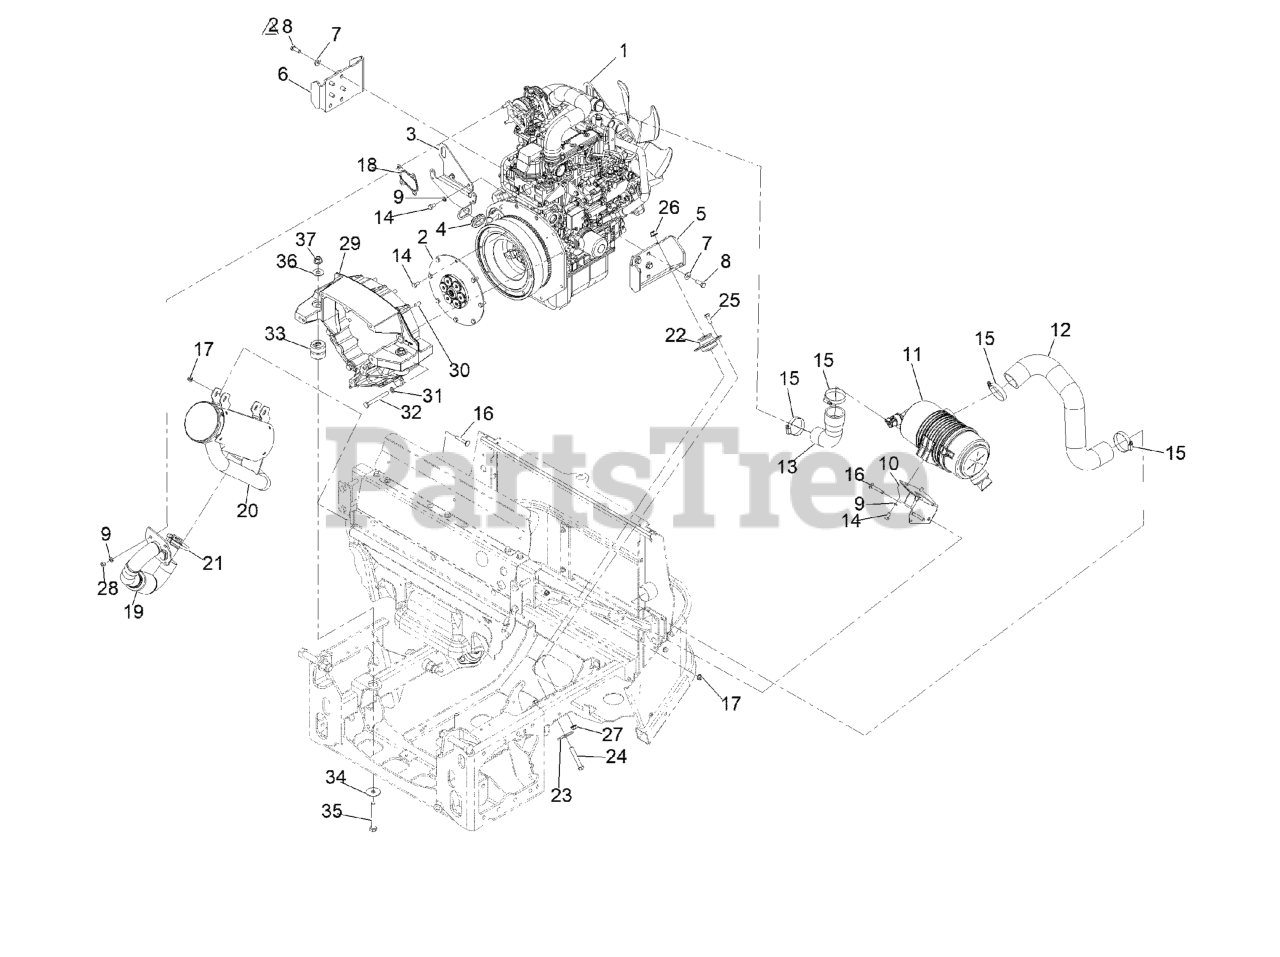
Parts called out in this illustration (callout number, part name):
1	Engine,Yanmar 3Tnv80Ft-Zmtr1
2	Flywheel Coupling ASM
3	BRACKET-GUIDE
4	GROMMET
5	MOUNT-ENGINE, LH
6	MOUNT-ENGINE, RH
7	WASHER-BELLEVILLE
8	SCREW-HH
9	WASHER-BELLEVILLE
10	BRACKET-CLEANER, AIR
11	ASM, HDAC
12	HOSE-AIR
13	HOSE-AIR
14	BOLT
15	CLAMP-HOSE
16	BOLT-CARR
17	NUT-HF, NI
18	GASKET-HEADER
19	HEADER PIPE
20	MUFFLER
23	WASHER-SNUBBING
24	SCREW-HH
25	SCREW-HH
26	NUT-HF, NI
27	NUT-HF, NI
28	NUT-HEX
29	Housing-Flywheel
30	PIN-DOWEL
31	WASHER-LOCK
32	SCREW-HH
33	MOUNT-ISOLATOR
34	WASHER-THRUST
35	SCREW-HH
36	WASHER-FLAT
37	Nut-Lock 1/2-13
